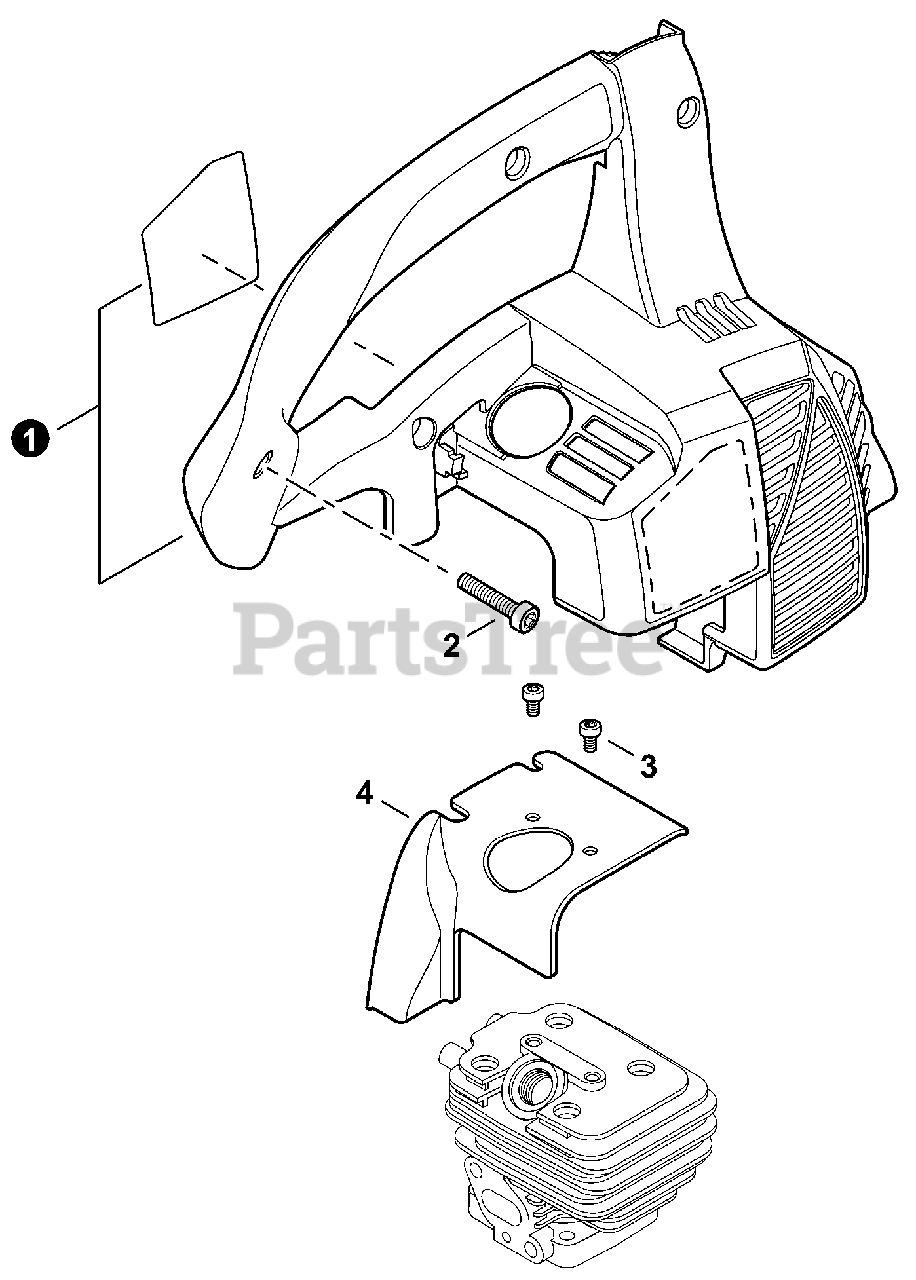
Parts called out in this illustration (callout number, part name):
1	COVER SET, ENGINE
2	BOLT, TORX 5×20
3	BOLT, TORX 5×8
4	SHIELD, CYLINDER
